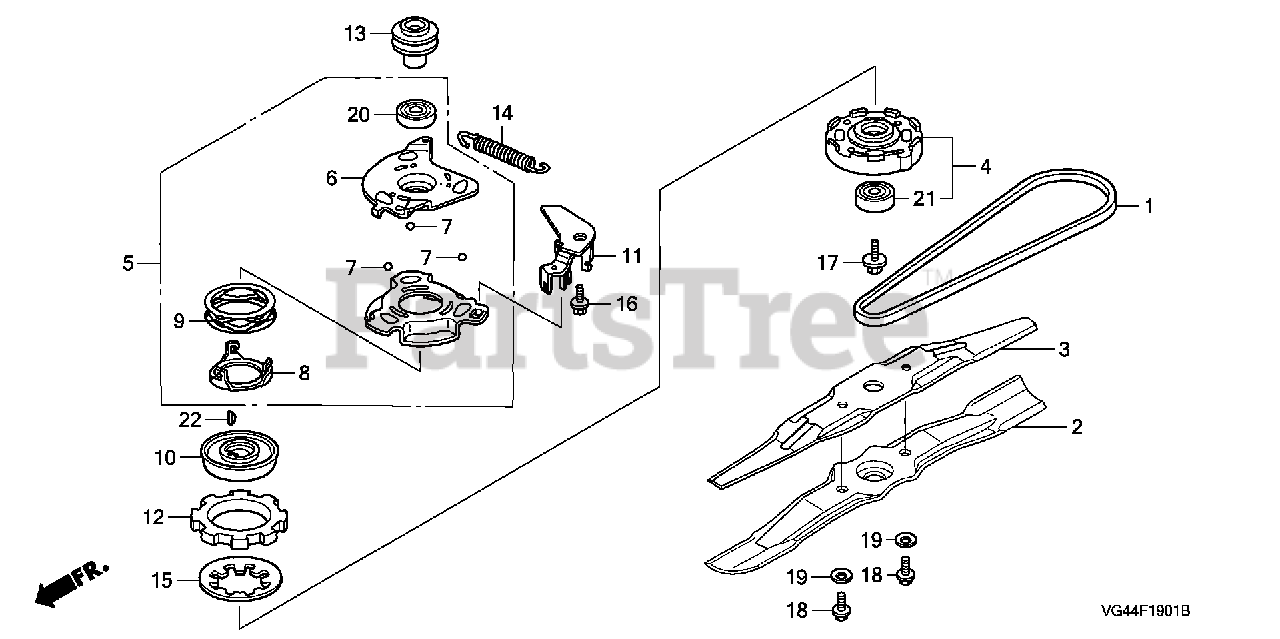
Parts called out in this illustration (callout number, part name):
1	V-BELT (3L-37)
2	BLADE, ROTARY
3	BLADE, ROTARY (UPPER) (PCD=88MM)
4	HOLDER ASSY., BLADE
5	PLATE ASSY., BALL CONTROL
6	PLATE, BALL CONTROL
7	BALL, STEEL
8	PLATE, SPRING HOOK
9	SPRING, BALL PLATE
10	DISK, DRIVE
11	HOOK, RETURN SPRING
12	DISK, DRIVEN
13	PULLEY, DRIVE
14	SPRING ASSY., CLUTCH RETURN
15	SPRING, CLUTCH
16	BOLT, FLANGE (6X14) (CT200)
17	BOLT, FLANGE (10X24)
18	BOLT, HEX. (10X20)
19	WASHER, SPRING (10MM)
20	BEARING, RADIAL BALL (6006) (SST)
20	BEARING, RADIAL BALL (6006) (TSB)
21	BEARING, RADIAL BALL (6204)
22	KEY, WOODRUFF (16X15)
